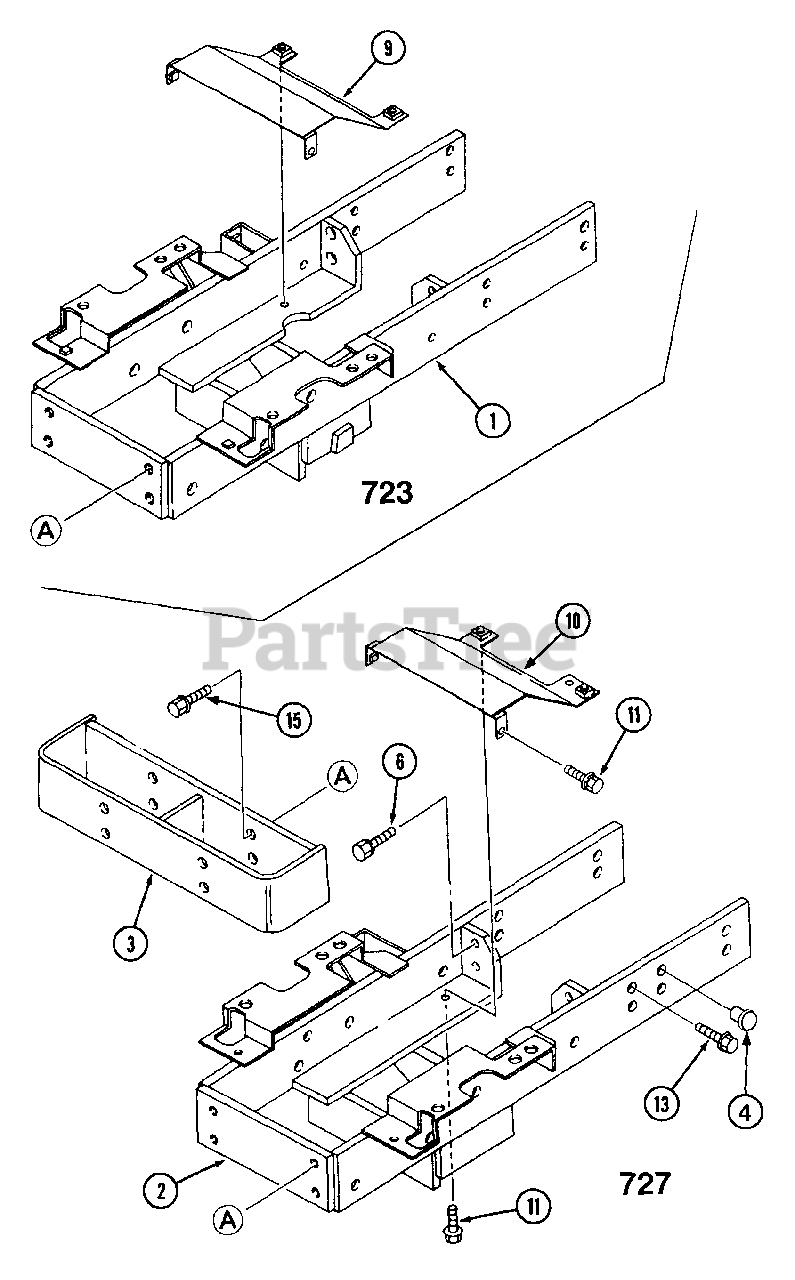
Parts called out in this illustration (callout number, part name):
1	Bracket, Front
2	Bracket, Front
3	Bracket, Weight
4	Plug
10	Cover
